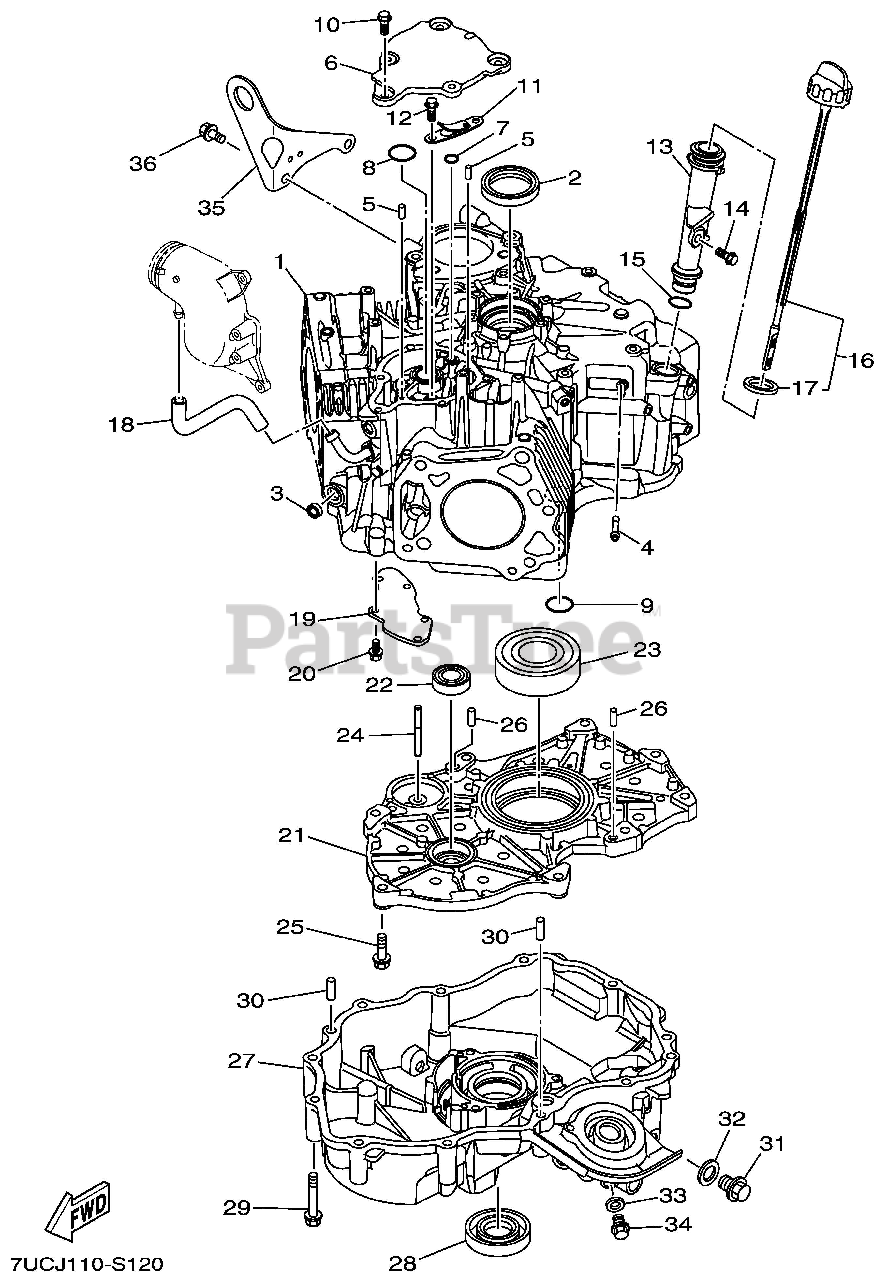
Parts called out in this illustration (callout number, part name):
1	CRANKCASE ASSY 1
2	OIL SEAL
3	OIL SEAL
4	PIPE, JOINT
6	COVER, AIR CLEANER
10	BOLT, FLANGE
11	REED VALVE ASSY
12	BOLT, FLANGE
13	PIPE, OIL
14	BOLT, FLANGE
16	GAUGE, LEVEL
20	BOLT, FLANGE
21	COVER, CRANKCASE 1
24	SHAFT, FLYWEIGHT
25	BOLT, FLANGE
26	PIN, DOWEL
27	COVER, CRANKCASE 2
28	OIL SEAL
29	BOLT, FLANGE
30	PIN, DOWEL
31	PLUG, STRAIGHT SCREW
34	BOLT, FLANGE
35	HANGER, ENGINE 2
36	BOLT, FLANGE
